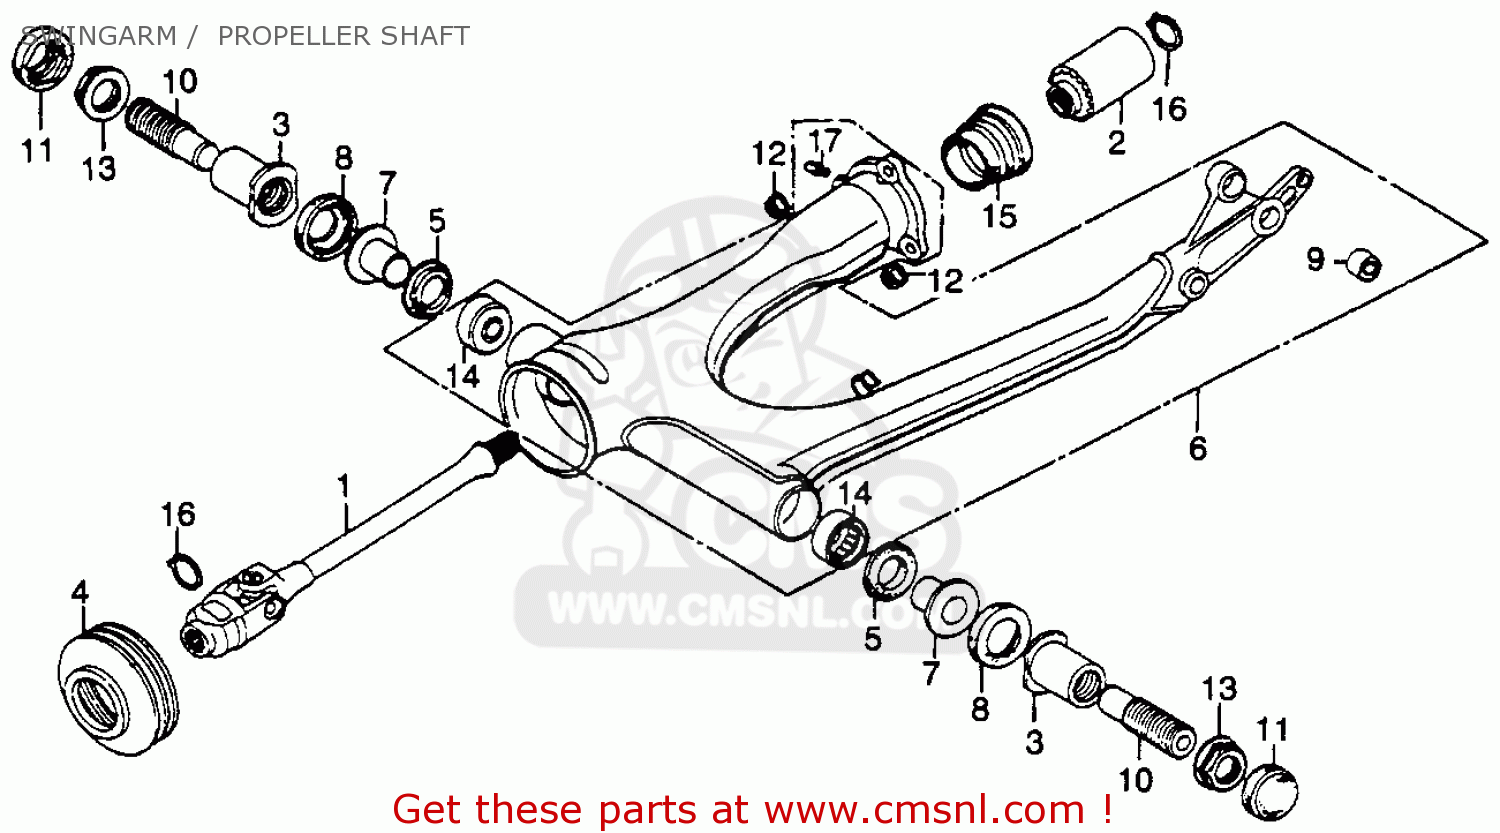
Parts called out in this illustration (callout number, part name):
1	SHAFT COMP.,PROP.
2	JOINT, SHAFT
3	NUT, FORK PIVOT
4	BOOT, JOINT
5	BUSH, PIVOT
6	SWINGARM, RR. *NH1*
7	COLLAR, PIVOT
8	COVER,PIVOT DUST
9	BUSH,REAR DAMPER
10	BOLT,PIVOT
11	CAP, LOCK NUT
12	NUT,HEX.,10MM
13	NUT, LOCK, 23MM.
14	NEEDLE BRG
15	OIL SEAL,43X67X32
16	CIR CLIP,EX.20
17	NIPPLE, GREASE, 6
